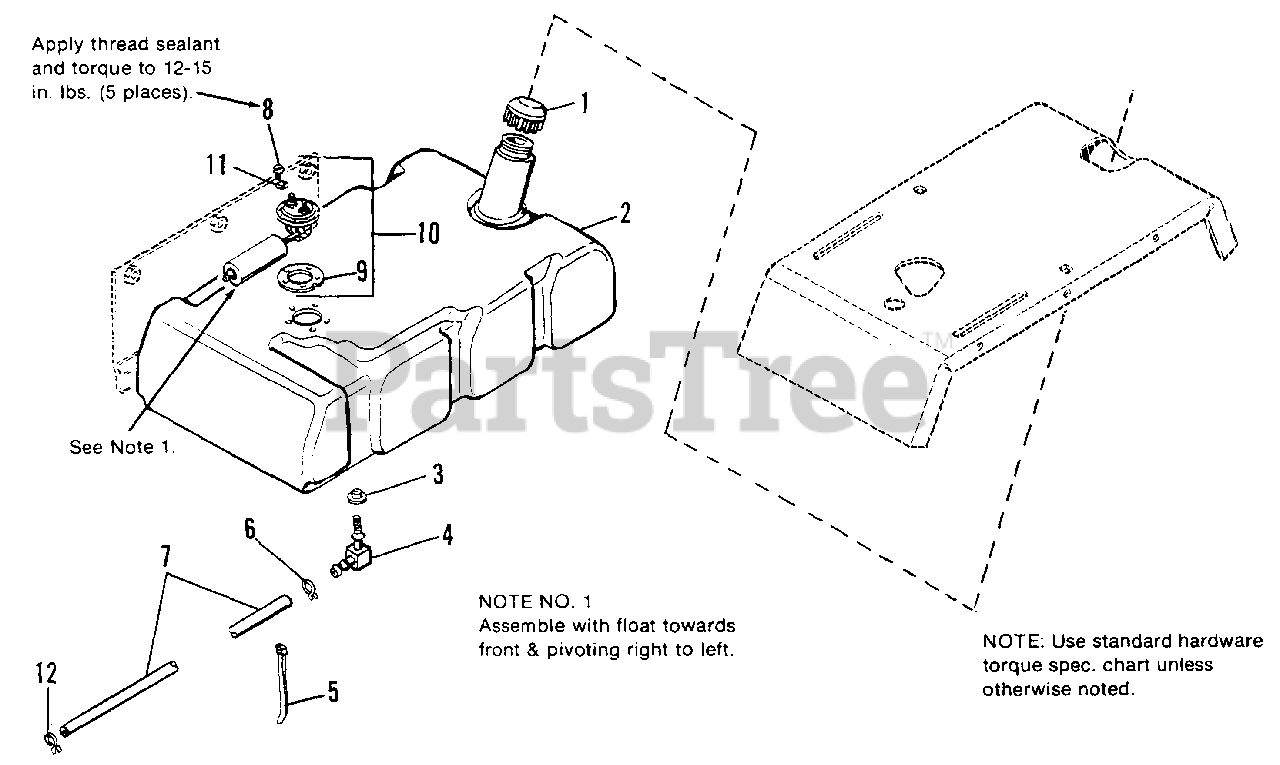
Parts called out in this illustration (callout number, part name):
1	CAP, Gas, Vented
2	*Fuel TANK & FITTINGS (Incl. Ref. Nos. 3, 4)
4	ELBOW, with Screen
5	TIE, Self-Locking
6	CLAMP, Hose
7	HOSE, Fuel, 1/4 I.D. x 45-1/2 LG.
8	SCREW, Truss Hd., #10-32 x 1/2
9	GASKET, Fuel Sender
10	SENDER, Fuel Level
11	LOCKWASHER
12	CLAMP, Hose
